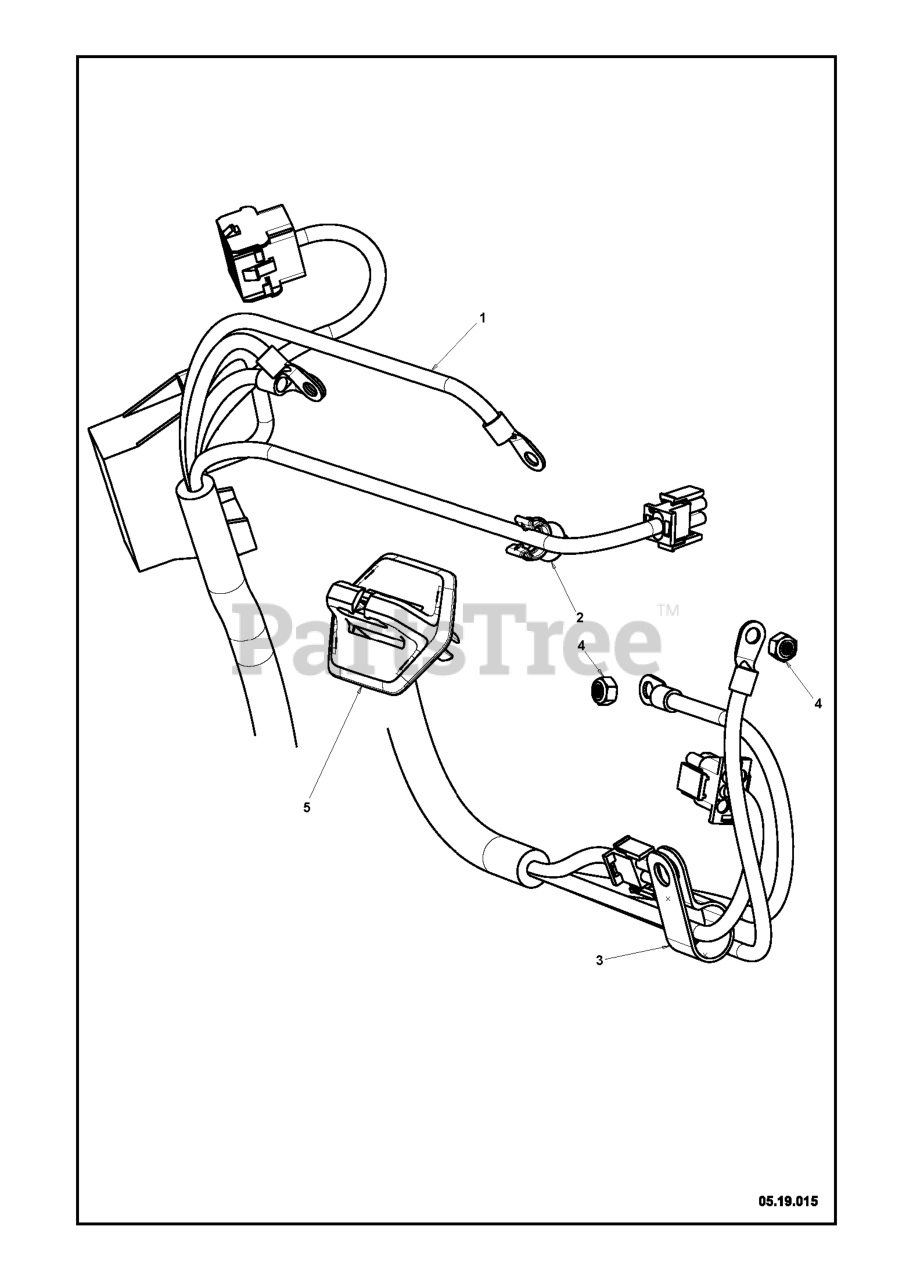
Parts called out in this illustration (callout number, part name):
2	CLIP CONVOLUTED TUBE, 1/4 BLAC
3	CLIP.CABLE.BLK
4	NUT LOCK NUT M6 NYLOC INSERT H
